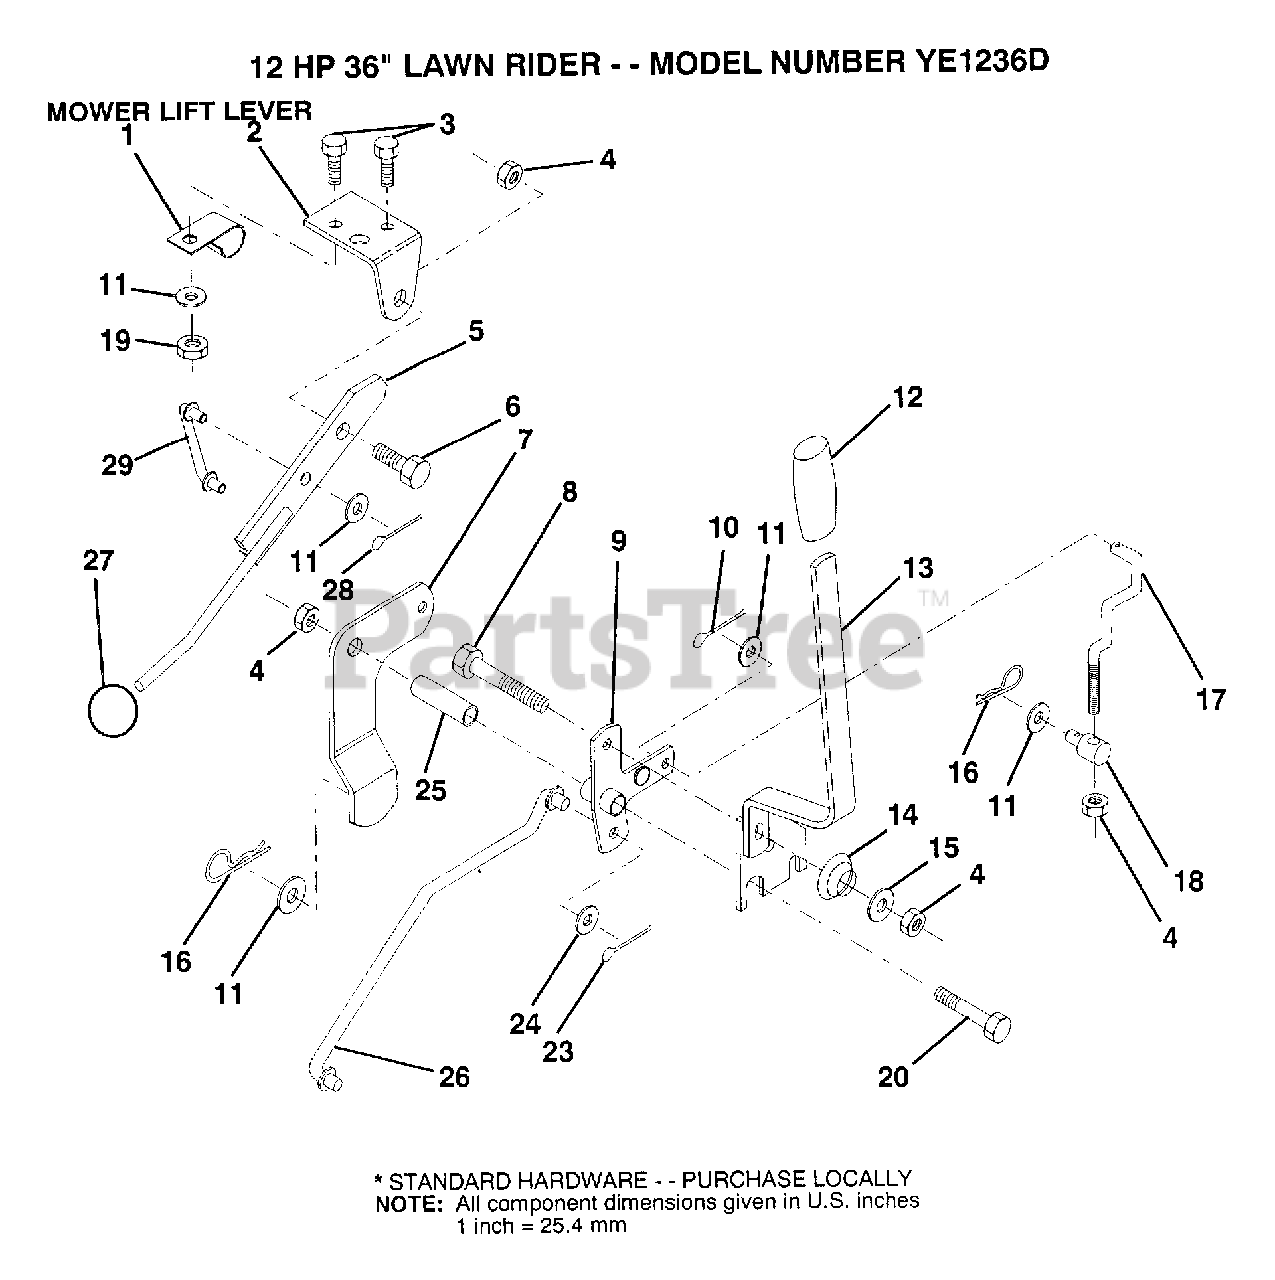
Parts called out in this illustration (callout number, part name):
1	"CLIP,INSULATOR"
2	BRKT CLUTCH
3	BOLT
5	CLUTCH LEVER AS
6	"BOLT, SHOULDER LT"
8	BOLT
9	"BELLCRANK,LIFT"
10	COTTER PIN
11	WASHER
12	GRIP HANDLE
13	"HDLE,LIFT T"
14	SPRING COMPRESSIO
15	WASHER T
16	SPRING.RETAINER
17	"LINK,LIFT FRT"
18	TRUNION
20	BOLT
23	PIN COTTER 1/8
25	TUBE SPACER
26	"ROD,MOWER LIFT "
27	KNOB
29	CLUTCH LINK
